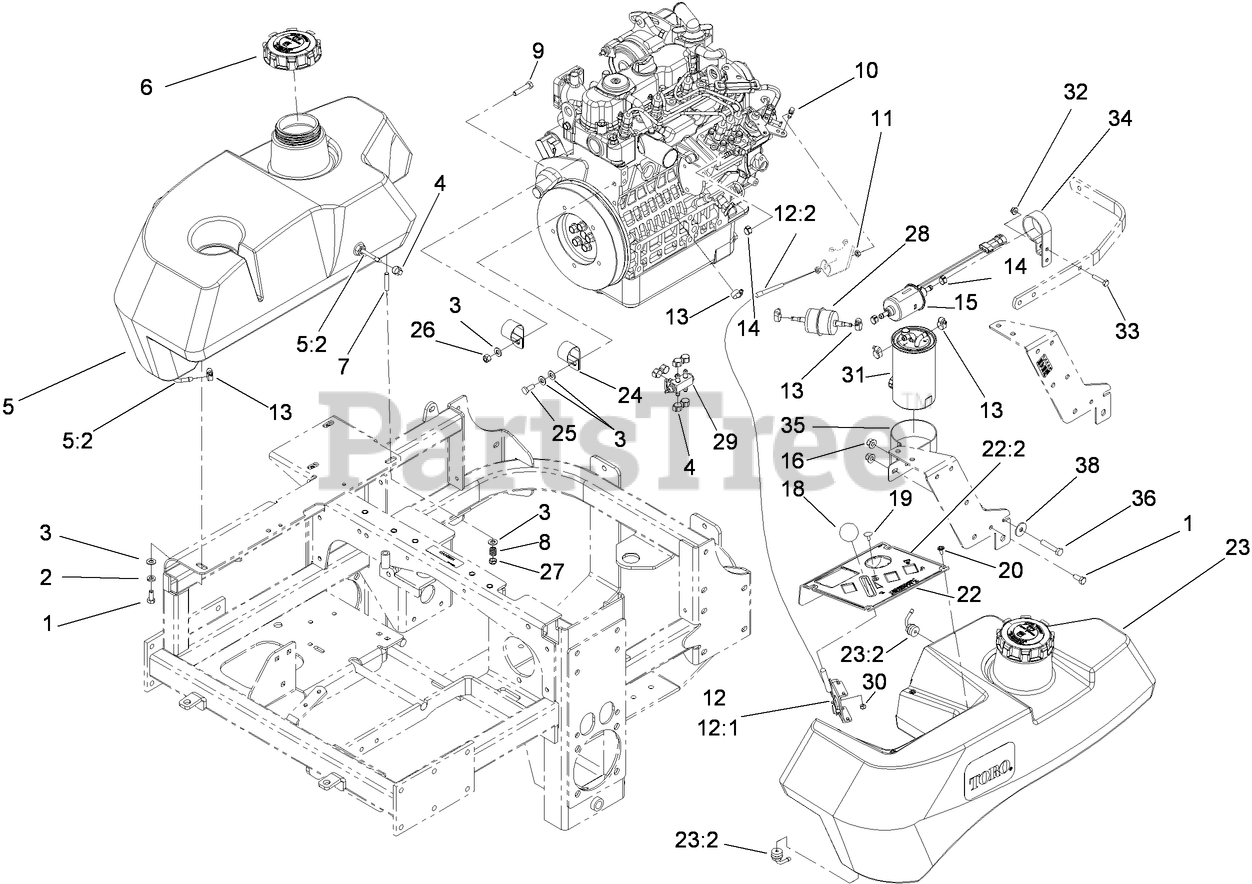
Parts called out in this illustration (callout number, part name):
1	SCREW-HH
2	WASHER-LOCK
3	WASHER-PLAIN
4	CLAMP-HOSE, FUEL
5	RH FUEL TANK ASM
5:2	Fitting-Fuel, Bulkhead
6	CAP-BIODIESEL
8	SPRING-TANK, FUEL
9	SCREW-HH
10	SWIVEL-STOP, CABLE
11	NUT-JAM
12	CABLE-CONTROL, THROTTLE
12:1	LEVER-CABLE, THROTTLE
12:2	CABLE-THROTTLE
13	CLAMP-WORM
14	CLAMP-HOSE, FUEL
15	PUMP-FUEL
16	NUT-LOCK, NI
18	KNOB-BALL
19	BOLT-CARR
20	SCREW-PPH
22	CONTROL PANEL ASM
22:2	DECAL-PANEL, CONTROL
23	LH FUEL TANK ASM
23:2	Fitting-Fuel, Bulkhead
24	CLIP-LOOM
25	SCREW-HH
26	NUT-LOCK, NI
27	NUT-LOCK, NI
28	FILTER-INLINE
29	VALVE-FUEL, DUAL FLOW
30	NUT-LOCK, NI
31	ELEMENT-FILTER, FUEL/WATER
32	NUT-HF
33	SCREW-HH
34	BRACKET-PUMP, FUEL
35	BRACKET-FILTER, FUEL
36	SCREW-HH
38	WASHER-FLAT
